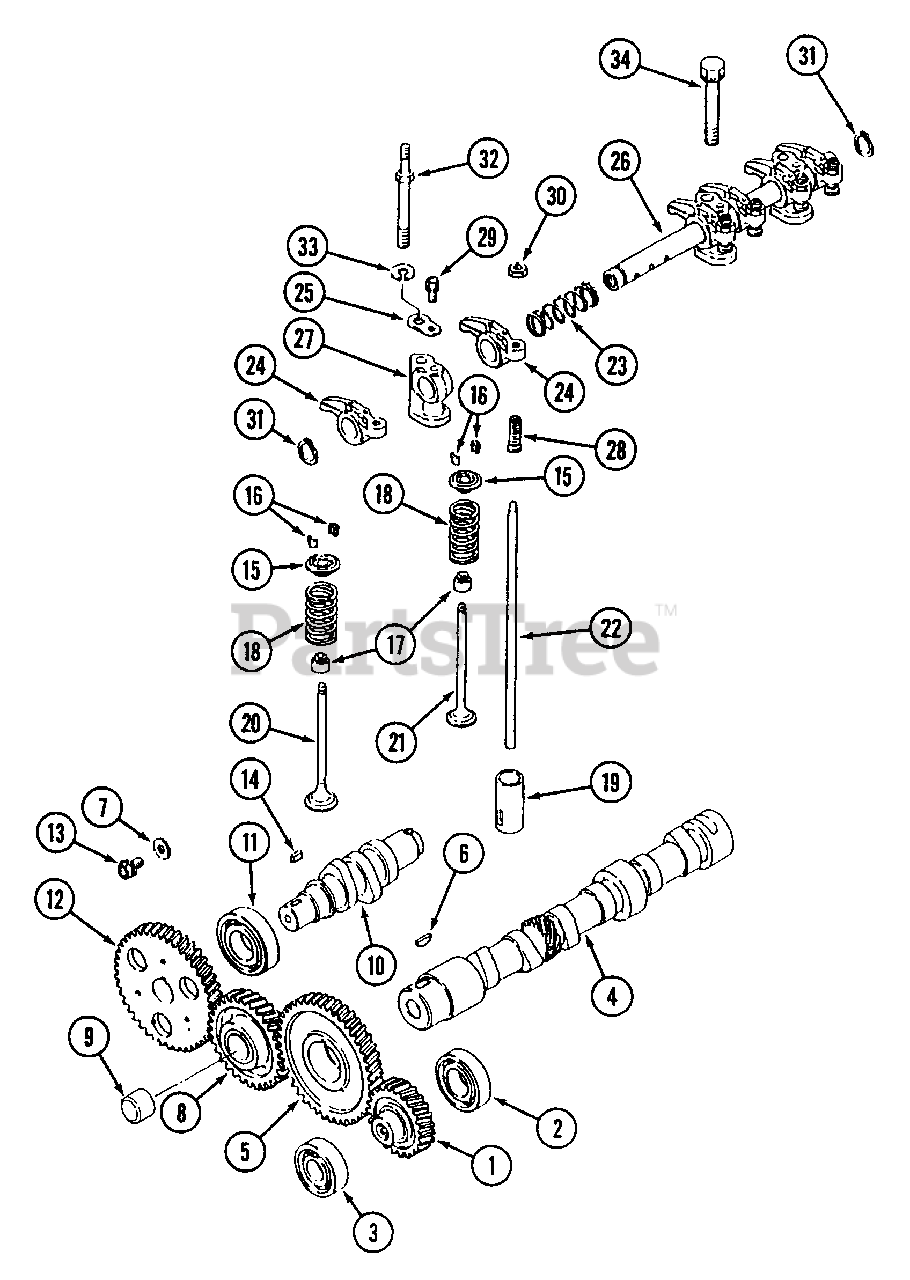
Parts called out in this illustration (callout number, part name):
1	Gear, Press, Oil Pump
2	Bearing, Ball
3	Bearing, Ball
5	Gear, Camshaft
6	Key, Woodruff
8	Idler Gear Ass'y.
9	Bushing, Idler Gear
10	Shaft, Inj-Pump Cam
11	Bearing, Ball
12	Gear, Inj-Pump Cam
13	Bolt w/Washer
15	Retainer, Valve, Spring
16	Lock, Retainer
17	Seal, Valve, Stem
18	Spring, Valve
19	Tappet
20	Valve, Intake
21	Valve, Exhaust
23	Spring, L.H. Rocker Shaft
24	Arm, Rocker
25	Washer Seat
26	Rocker, Shaft Ass'y.
27	Stay, Rocker
28	Screw, Adjusting
29	Bolt w/Washer
30	Nut, Jam
31	Ring, Snap
33	Washer, Spring
34	Bolt w/Washer
